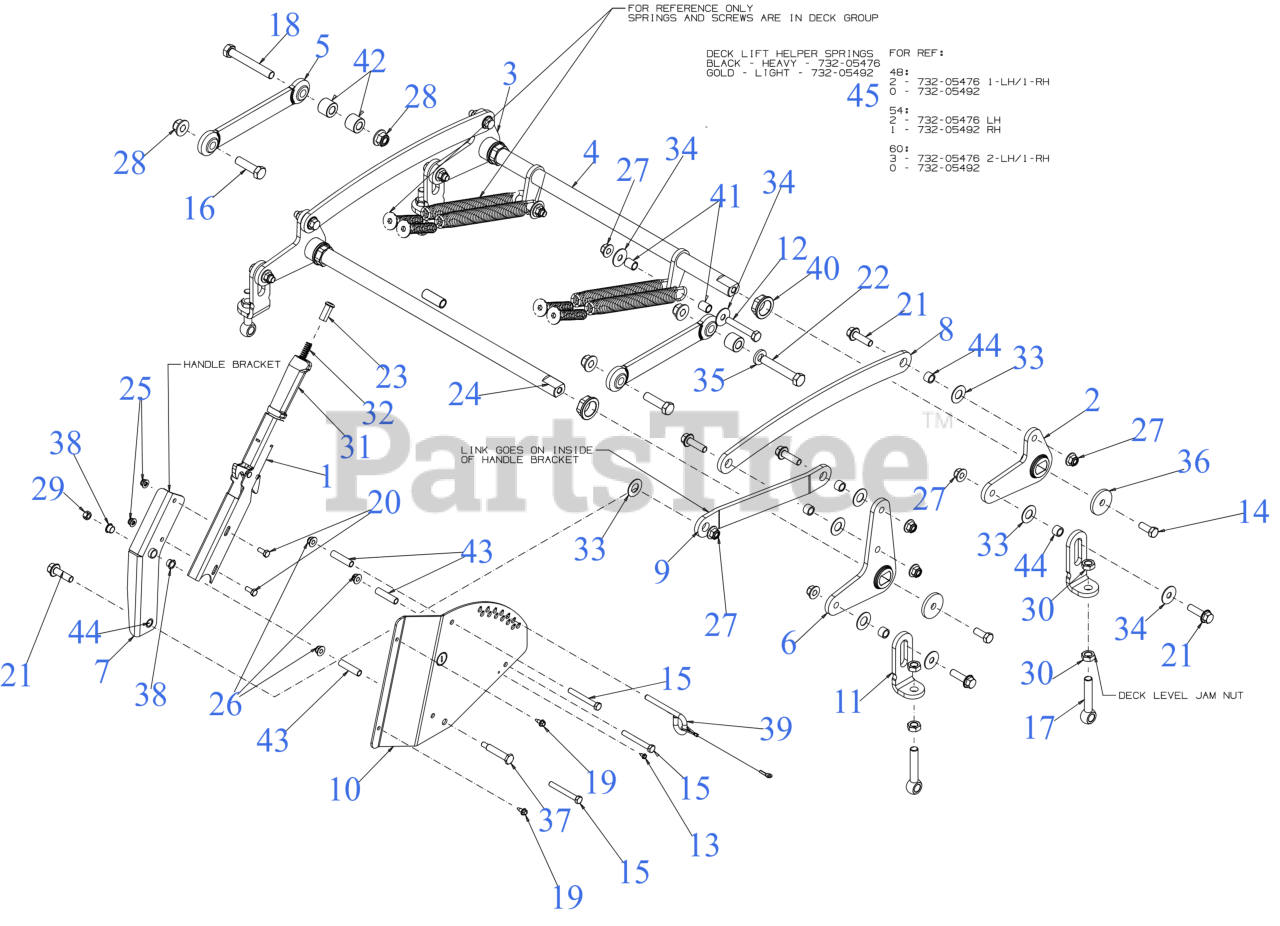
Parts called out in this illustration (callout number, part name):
1	LATCH HANDLE ASSEMBLY
4	DECK LIFT SHAFT
5	DECK CONTROL ROD
6	DECK LIFT BELLCRANK (RH)
7	DECK LIFT HANDLE
9	DECK LIFT LINK
10	INDEX PLATE
11	ADJUSTMENT ARM
12	SCREW-HEX 1/2-13 x 3.00
13	HEX SCREW AB-TAP #10 x .50
14	SCREW 1/2-13 x 1.25 GR5
15	SCREW 3/8-16 x 3.0 GR5
16	SCREW 5/8-11 x 2.25 GR5
18	EYE BOLT 5/8-11 x 3.63
18	SCREW 5/8-11 X 4.5 GR5
19	SCREW 1/4-20X.625
20	SCREW 5/16-18 x .75 GR5
21	FLANGE BOLT 1/2-13:1.75:GR5
22	SCREW 5/8-11 x 3.75 GR5
23	LIFT HANDLE BUTTON
24	DECK LIFT SHAFT
25	FLANGE LOCK NUT 5/16-18
28	FLANGE LOCK NUT
29	LOCK NUT 3/8-16
31	LIFT HANDLE GRIP
32	COMPRESSION SPRING
33	FLAT WASHER .760ID X1.49OD x .06
34	WASHER .51 x 1.5 x .07
35	FLAT WASHER .635 x 1.24 x .181
36	FLAT WASHER .53"x2.125"x.25"
37	SHOULDER SCREW .50 x 2.23 3/8-16
38	NYLINER BEARING
40	FLANGE BEARING
41	SPACER 0.535 x 0.68 x 0.83
42	SPACER 0.630x1.25x1.00LG
43	SPACER .38 ID x .50 OD x 2.06 LG
45	EXTENTION SPRING 1.20 x 11.35
45	EXTENSION SPRING 1.44 OD x 11.36
